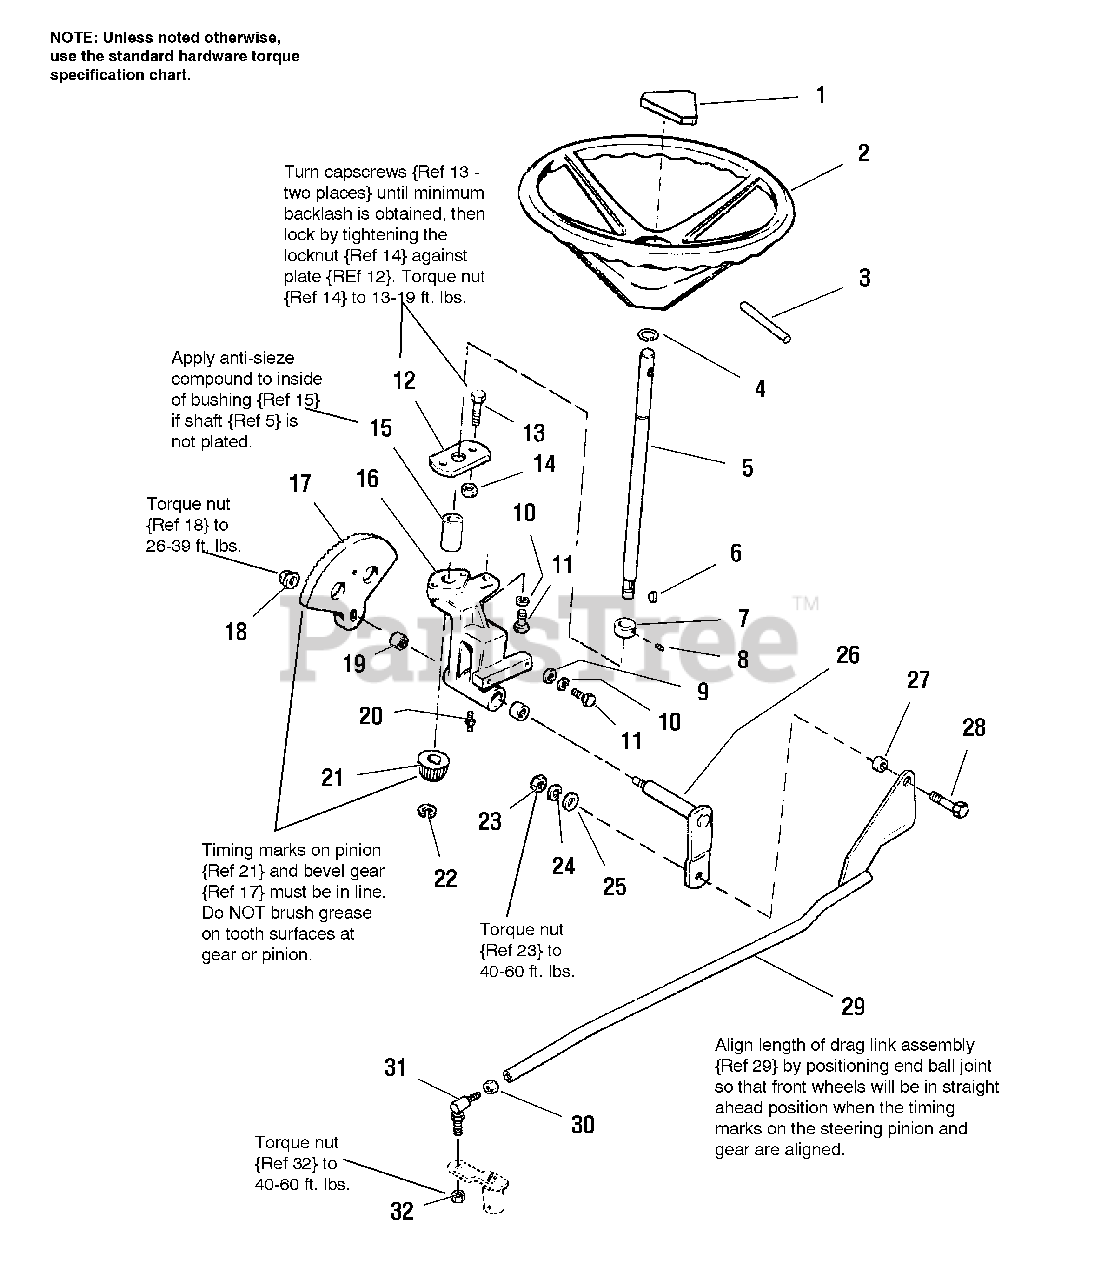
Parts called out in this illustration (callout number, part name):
1	CAP, Steering Wheel
2	WHEEL ASSEMBLY, Steering, 15
3	PIN, Spring, 5/16 x 2
4	RING, Retaining
5	SHAFT, Steering
6	KEY, Woodruff, #6
7	COLLAR, Set
8	SETSCREW, 5/16-18 x 1/4
9	WASHER, Bevel, 3/8
10	LOCKWASHER, 3/8
11	CAPSCREW, Hex Hd, 3/8-16 x 1
12	PLATE, Steering
13	CAPSCREW, Hex Hd, 3/8-16 x 1-1/4
14	LOCKNUT, Hex, Jam, 3/8-16
16	HOUSING ASSEMBLY, Steering
17	GEAR, Steering
18	LOCKNUT, Hex, Flange, 7/16-14
19	BEARING, Needle
20	FITTING, Grease
21	PINION, Bevel
22	E-RING
23	NUT, Hex, Full, 1/2-13
24	LOCKWASHER, 1/2
25	WASHER, Plain, 1/2
26	ARM ASSEMBLY, Steering
28	CAPSCREW, Hex Hd., 1/2-13 x 1-1/2
29	LINK ASSEMBLY, Drag
30	LOCKNUT, Hex, Jam, 1/2-20
32	LOCKNUT, Hex, 1/2-20
